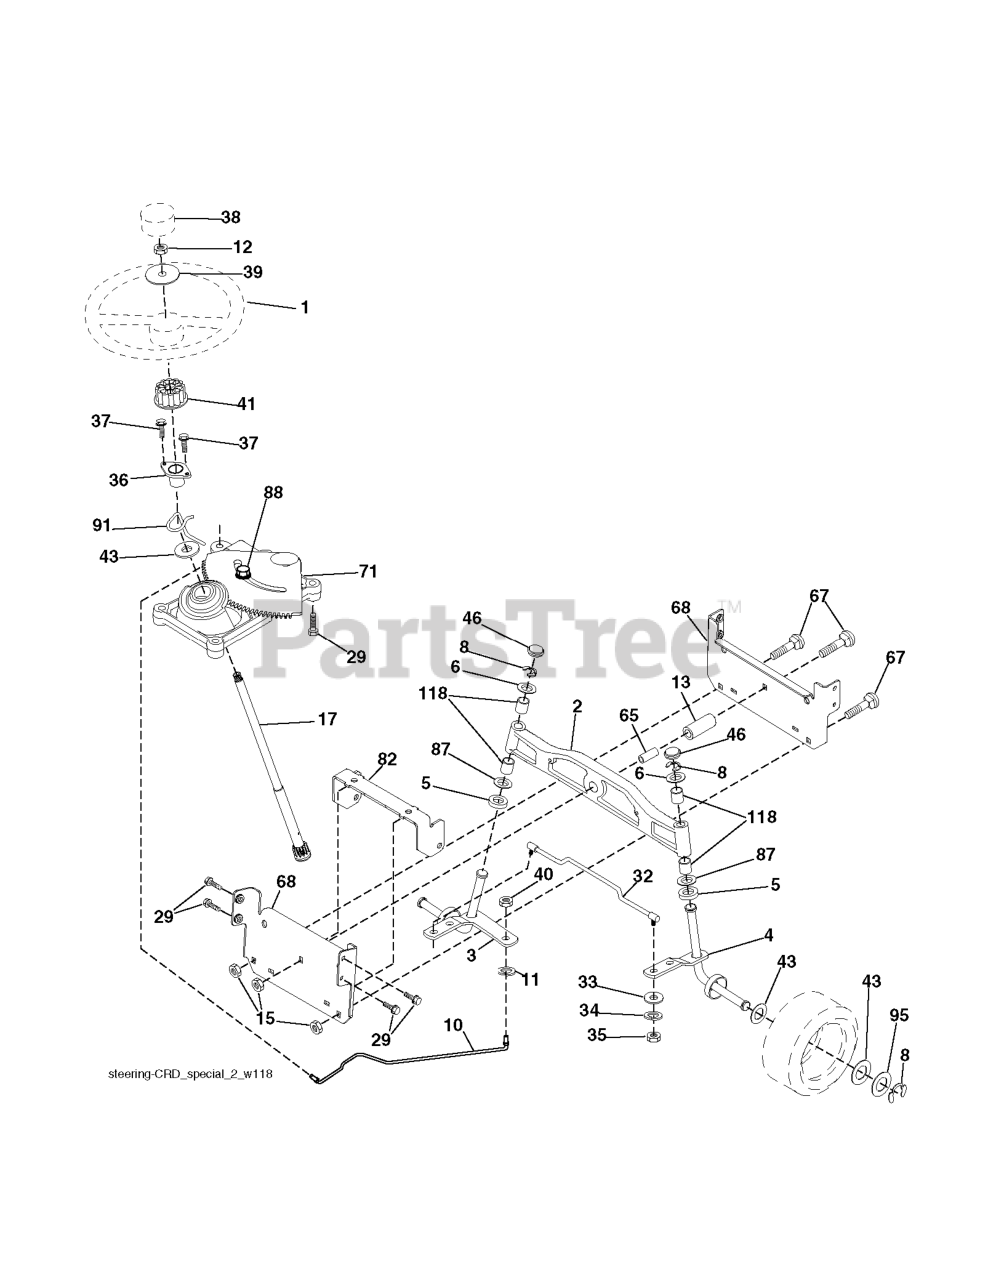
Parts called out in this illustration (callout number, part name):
1	RP WHEEL.STEER.HUSQ.PREM.OVMLD
2	AXLE ASSY FRONT
3	SPINDLE.ASM.LH.15"TIRES
4	SPINDLE.ASM.RH.15"TIRES
5	THRUST WASHER
10	DRAGLINK.15".TIRES.2001
11	WASHER, LOCK 3/8
12	NUT.HEX.1/2-20
13	TUBE, PIVOT AXLE
15	NUT
17	SHAFT ASM STRG
29	SCREW, 3/8-16X3/4
33	WASHER M
34	WASHER.LOCK.HVY.HLCL.SPR.5/16
35	NUT, CROWNLOCK
36	BUSHING, STRG. BLK
37	SCREW.TT.#10-32X.5.3/8.FLANGE
38	RP INSERT.CAP.WHL.STRG.HUSQ.
39	WASHER 9/16"ID, 2 3/8"OD
40	NUT CROWNLOCK 3/8-24
41	ADAPTER, WHEEL STNG..
46	CAP.SPINDLE.BLACK
65	SPACER BRACE AXLE
67	BOLT CARRIAGE
68	BRACE.AXLE.15"TIRES
71	STEERING ASM
82	BRACKET.SUSP.CHASSIS.FRONT.15
87	WASHER, FLAT .781 X 1 1/2"
88	BOLT, SHOULDER 7/16-20
91	CLIP.STEERING
95	WASHER.HARDENED
118	BUSHING, AXLE CAST
